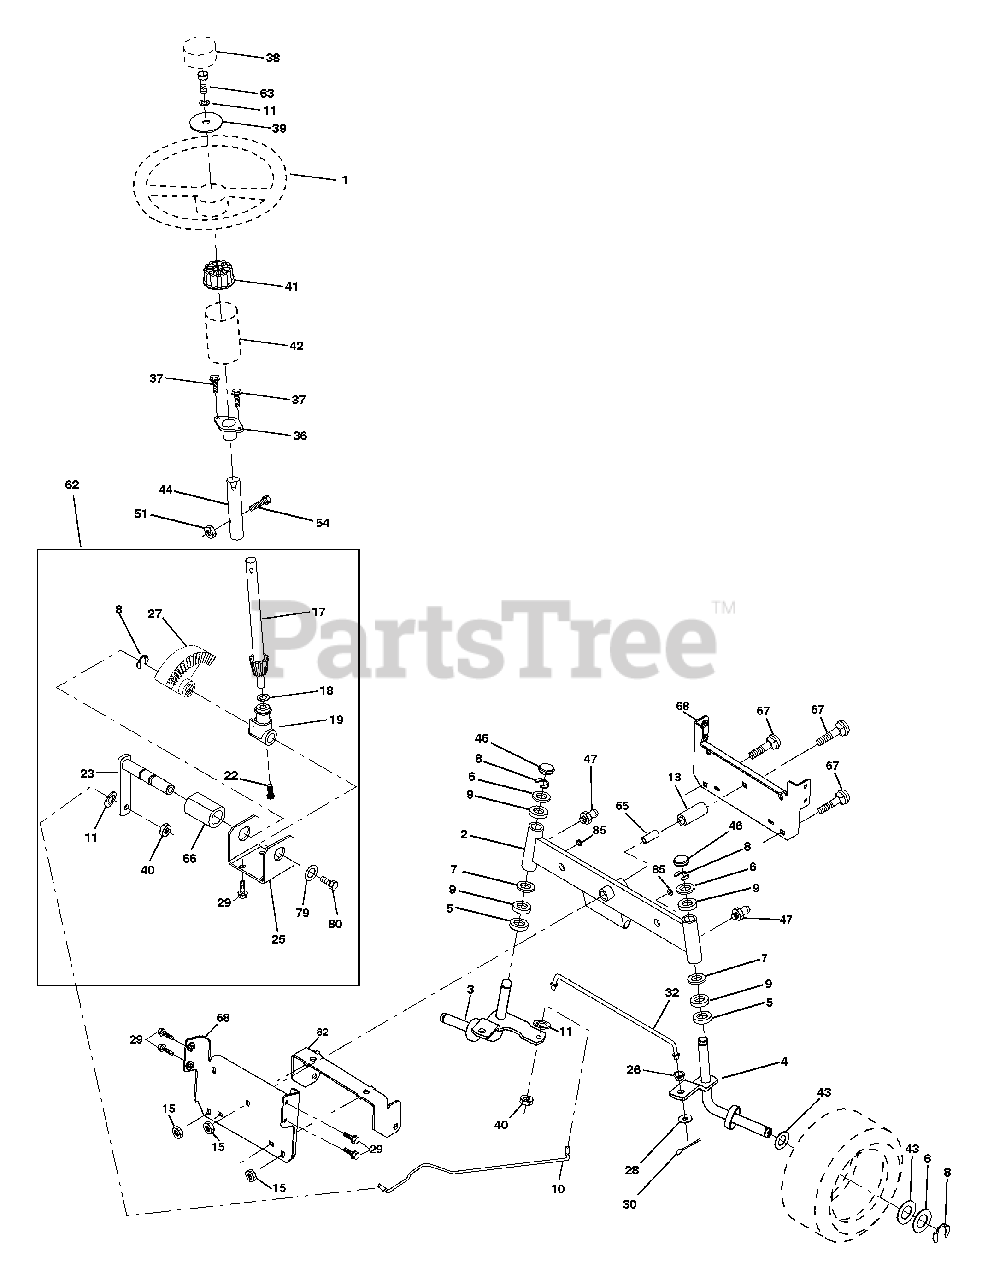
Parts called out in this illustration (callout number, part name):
1	Wheel Steering Ayp/P/L Blk
2	Axle Asm
3	Spindle Asm LH
4	Spindle Asm RH
5	Bearing Race Thrust Harden
6	Washer 25/32 X 1-5/8 X 16 Ga
7	Washer 27/32 X 1-1/4 X 16 Ga
8	Ring Klip #t5304-75
9	Bearing Col Strg Blk
10	Link Drag
11	Washer Lock Hvy Hlcl Spr 3/8
13	Spacer earing Axle Front
15	Hex flange Lock
17	Shaft Asm Strg
18	Washer Thrust 515x 750x 033
19	Support Shaft
22	Screw Hex Wsh Hd Torx
23	Shaft Asm Pittman
25	Bracket Steering
26	Bushing Link Drag Blk LR
27	Gear Sector
28	Washer 13/32 X 7/8 X 16 Ga
29	Screw 3/8-16 x 3/4
30	Pin Cotter 1/8 X 3/4 Cad
32	Rod Tie Wire Form 19 75 Mech
36	Bushing Strg 5/8 Id Dash
37	Screw
38	Cap Wheel Steer Ayp
39	Washer 13/32 x 2-3/8 x 12 Ga.
40	Nut Lock Center 3/8-24un
41	Adaptor Wheel Strg
42	Boot Dash Mtl Steering Blk
43	Washer 25/32 X 1 1/4 X 16 Ga
44	Extension Steering
46	Cap Spindle Fr Top Blk
47	Fitting Grease
51	Nut Lock Hex W/Ins 5/16-18
54	Bolt Fin Hex 3/8-16unc x 1-1/4
62	Kit Steering Assembly Service
63	Bolt Fin Hex 3/8-16unc x 1 Gr.5
65	Spacer Brace Axle
66	Bearing Arm Pittman
67	Bolt Fin Hex 5/8-11 unc x 2-3/4
68	Brace Axle
79	Washer 13/32 x 1 1/4 x 12 Ga.
80	Bolt Hex 3/8-16 x 3/4
82	Bracket Susp Chassis Front
85	Fastener Christmas Tree
